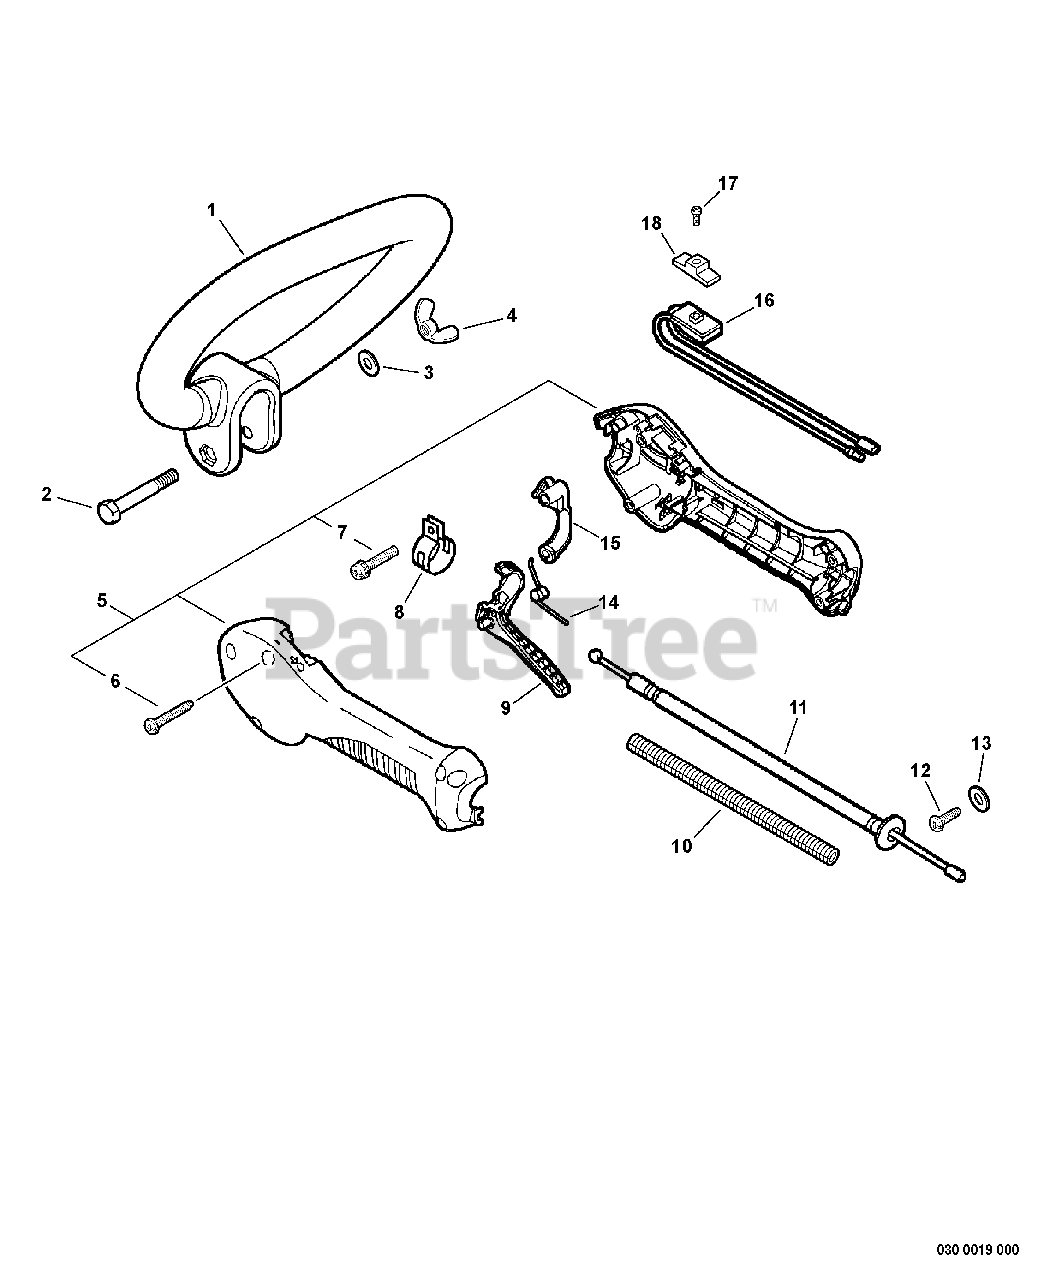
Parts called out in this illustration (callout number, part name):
1	HANDLE, SUPPORT
2	BOLT 1/4"-20×2"
3	WASHER, 1/4"
4	NUT, WING 1/4"-20
5	CONTROL HANDLE KIT
6	SCREW 5×20
7	SCREW 5×20
9	TRIGGER, THROTTLE
10	TUBE, FLEXIBLE
11	CABLE, THROTTLE
12	SCREW, TAPPING
14	SPRING, TORSION
15	LOCKOUT, THROTTLE
16	SWITCH, ON-OFF
17	SCREW 3×10
18	KNOB, SWITCH - ORANGE
